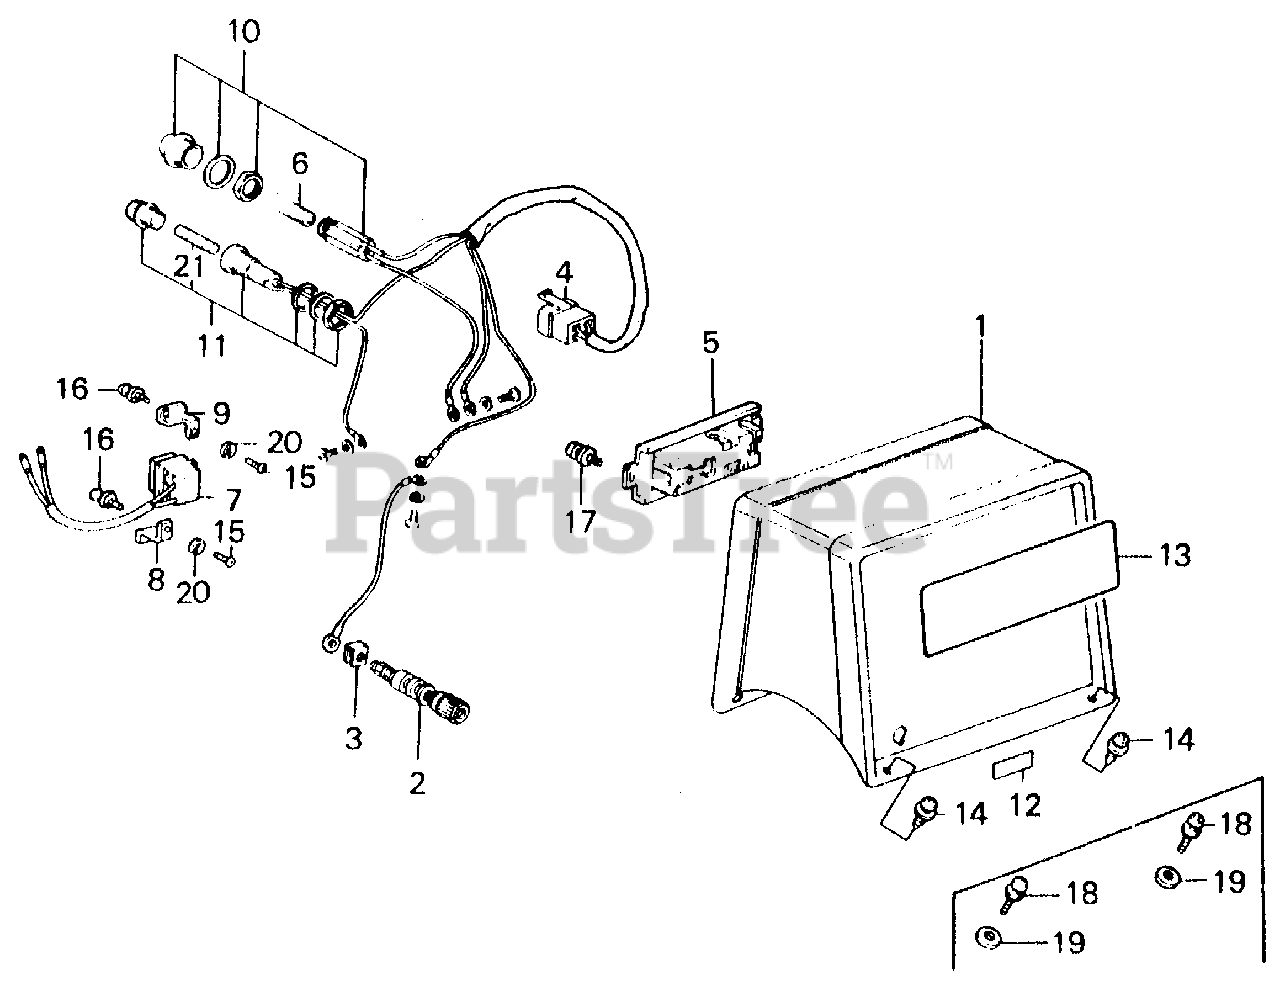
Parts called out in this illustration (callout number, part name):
1	BOX, CONTROL *R8* (BRIGHT RED)
2	TERMINAL ASSY., GROUND
2	TERMINAL ASSY., GROUND (NOT AVAILABLE)
3	PLATE, GROUND
4	CONNECTOR, MALE (4 POLE)
5	RECEPTACLE (15A 125V)
5	RECEPTACLE (15A-125V)
6	BULB (24V2W)
7	METER, FREQUENCY
8	HOLDER A, FREQUENCY METER
9	HOLDER B, FREQUENCY METER
10	SOCKET ASSY., PILOT LAMP (NOT AVAILABLE)
11	HOLDER ASSY., FUSE
12	MARK, GROUND
13	PLATE, CAUTION (NOT AVAILABLE)
14	SCREW, TAPPING (5X14)
15	SCREW, PAN (3X8)
16	SCREW-WASHER (4X10)
17	SCREW-WASHER (4X12)
18	SCREW-WASHER (5X16)
19	WASHER, PLAIN (5MM)
20	WASHER, SPRING (3MM)
21	FUSE (15A)
